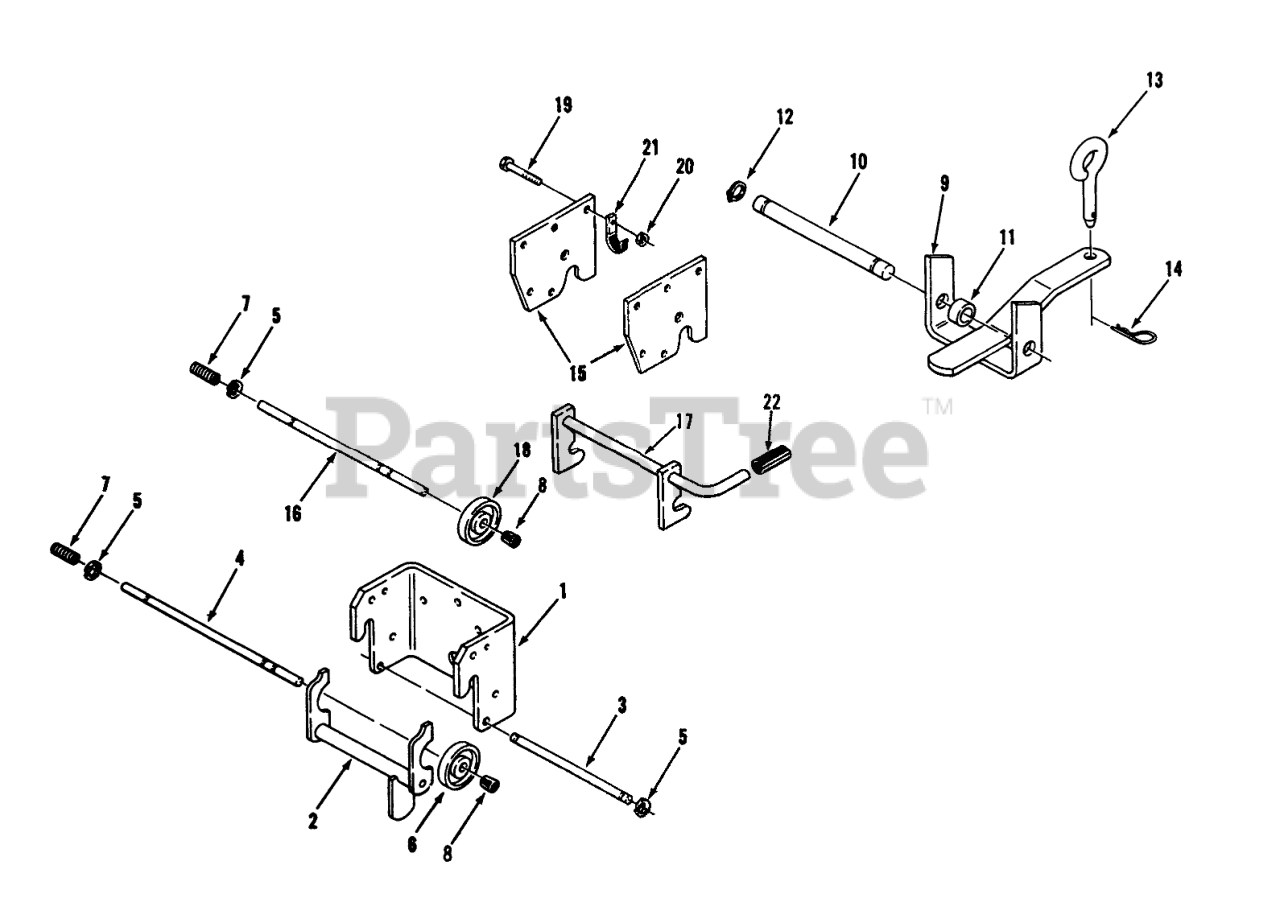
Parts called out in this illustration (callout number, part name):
1	Front Hitch
2	Assy-Latch
3	ROD-LATCH PIVOT
4	ROD-LOCK
5	RING-RETAINING
7	SPRING
8	CAP-ROD, PLUNGER
9	Hitch
10	PIN-STATIONARY HITCH
11	Spacer
12	E-RING
13	PIN-TOOL
14	Hairpin Cotter
15	Hitch Plate
16	ROD-LOCK
17	MID HITCH ASM
19	SCREW-HH
21	CLIP
22	GRIP
